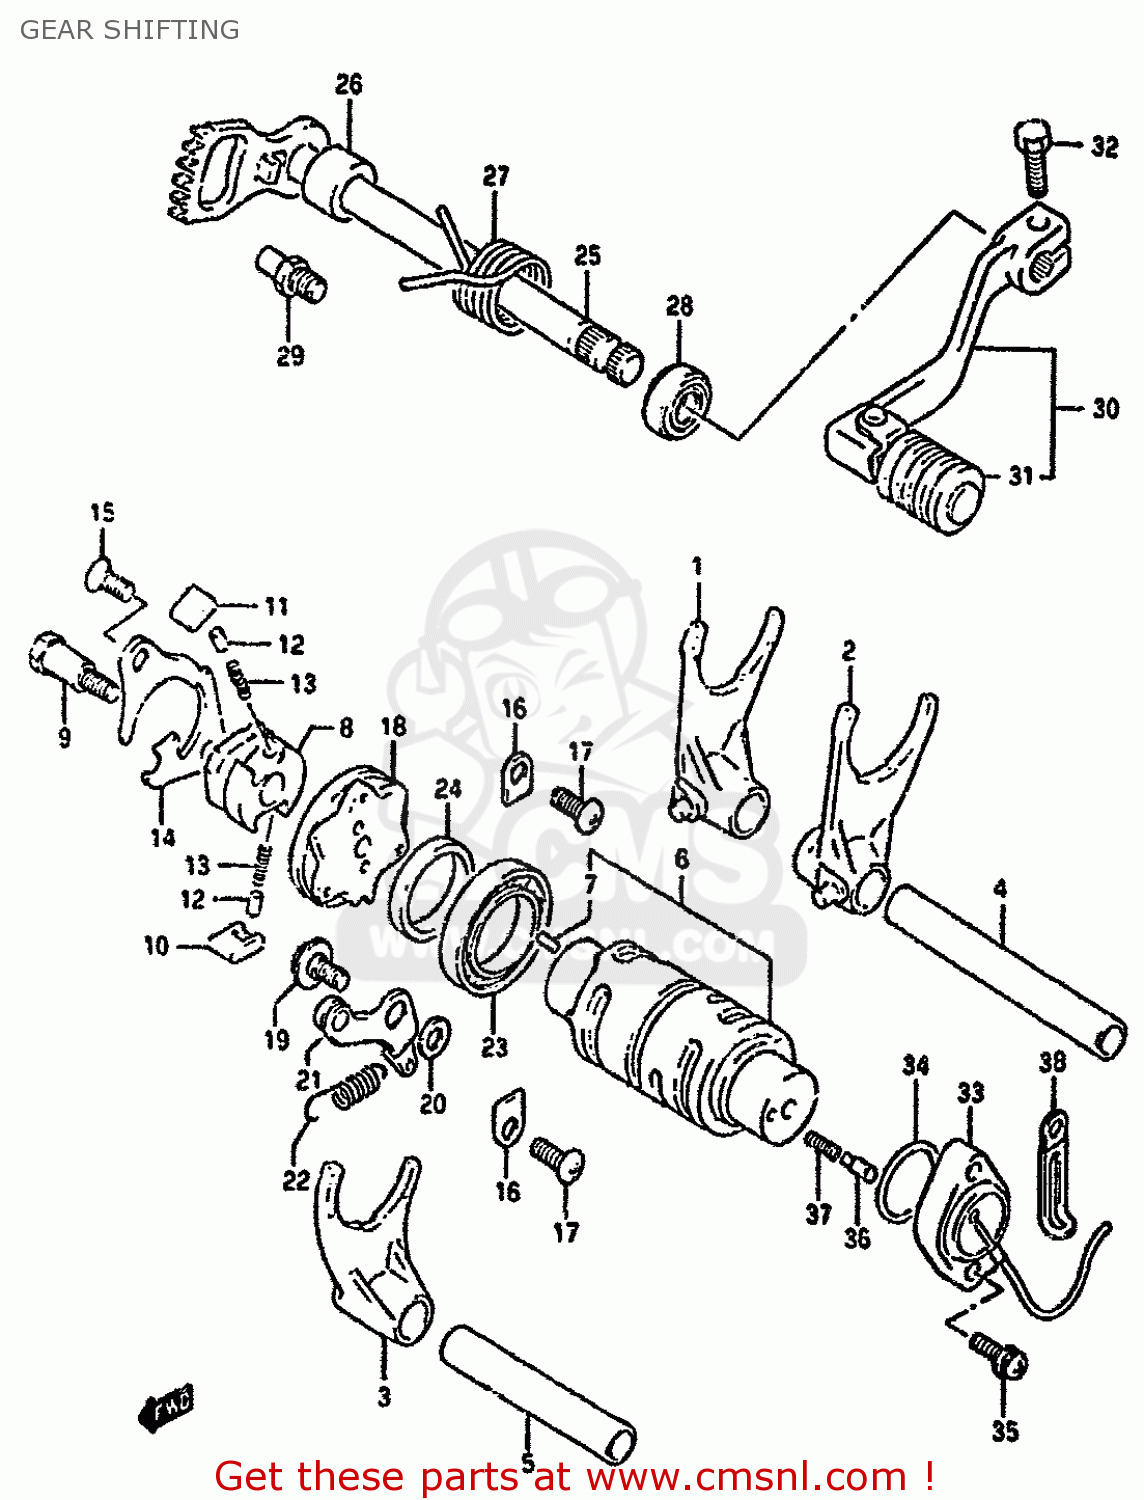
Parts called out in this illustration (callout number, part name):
1	FORK,GEAR SHIFT NO.1
2	FORK,GEAR SHIFT NO.2
3	FORK,GEAR SHIFT NO.3
4	SHAFT,GEAR SHIFT FORK
5	SHAFT,GEAR SHIFT FORK(L:70)
6	CAM,GEAR SHIFT
7	PIN
8	GEAR,GEARSHIFT CAM DRIVE
9	PIN,SHIFT CAM DRIVEN GEAR
10	PAWL,GEAR SHIFT NO.1
11	PAWL,GEAR SHIFT NO.2
12	PIN(5X8)
13	SPRING
14	LIFTER,GEAR SHIFT PAWL
15	SCREW
16	RETAINER
17	SCREW 6X12
18	PLATE,GEAR SHIFT CAM
19	BOLT(6X14.3)
20	WASHER
21	STOPPER,GEAR SHIFT CAM
22	SPRING
23	BEARING
24	WASHER(25X32X5.3)
25	SHAFT,GEAR SHIFT
26	SPACER(12X20X15.3)
27	SPRING
28	OIL SEAL
29	STOPPER,GEAR SHIFT ARM
30	LEVER ASSY,GEAR SHIFT
31	RUBBER,GEAR SHIFT PEDAL
32	BOLT
33	BASE ASSY,NEUTRAL SW TERMINAL
34	O RING(D:2.4,ID:26.2)
35	SCREW
36	PIN(5X15.5)
37	SPRING
38	CLAMP
